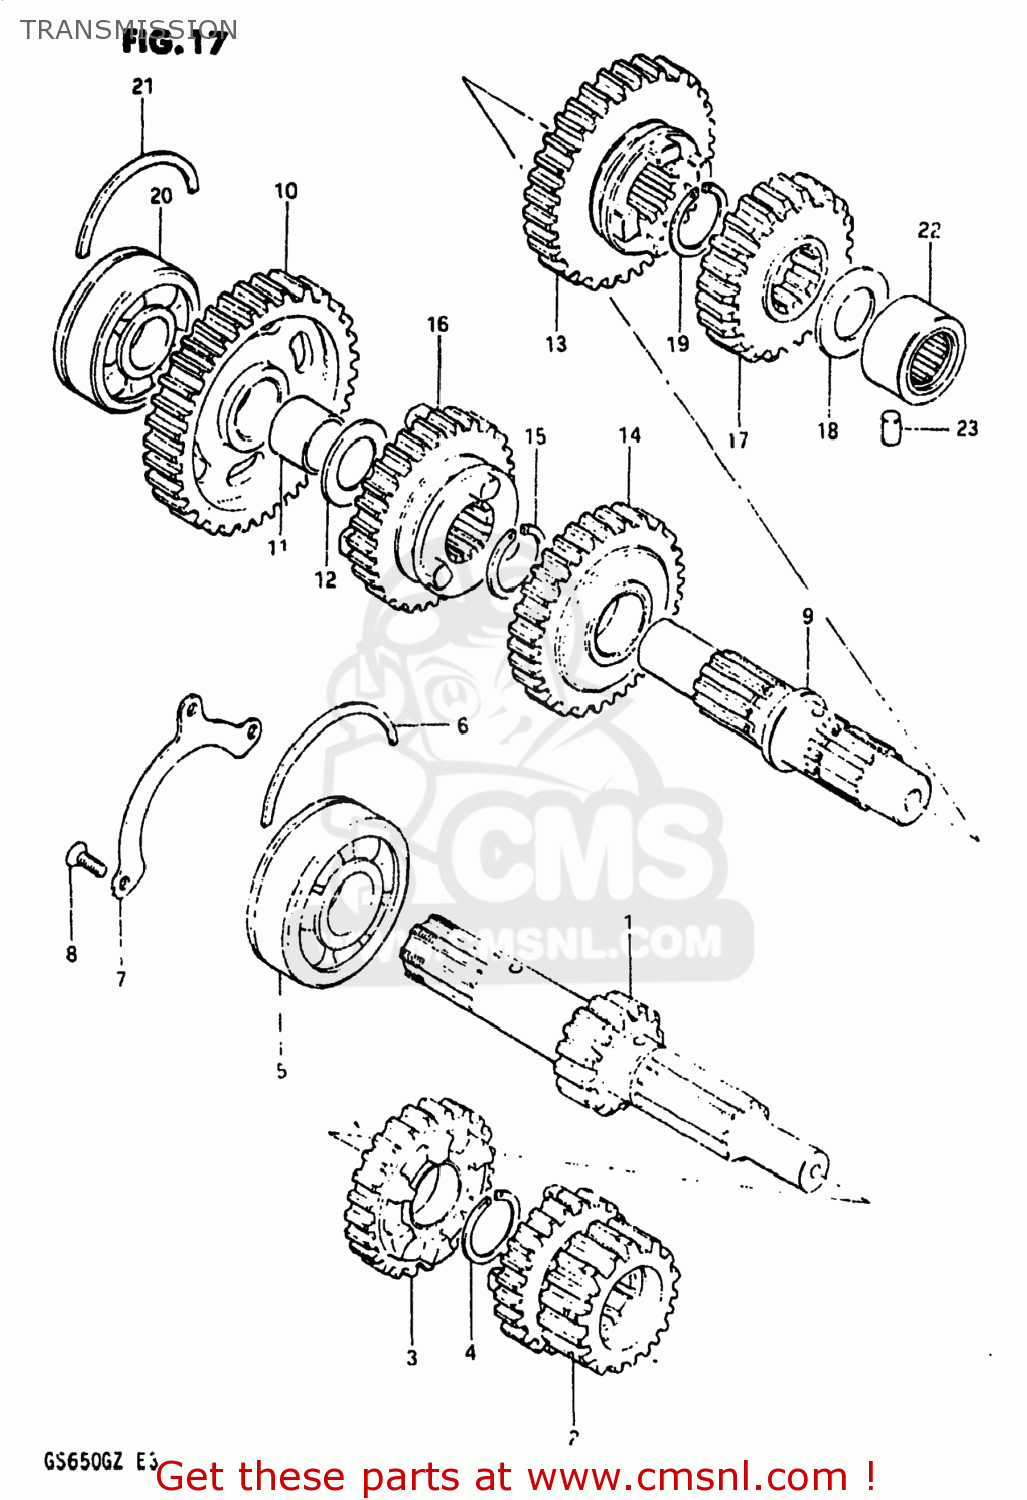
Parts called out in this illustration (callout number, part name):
1	SHAFT,COUNTER
2	GEAR,SECOND DRIVE
3	GEAR,FOURTH DRIVE
4	CIRCLIP
5	BEARING(25X62X17)
6	C-RING
7	RETAINER,CNTR SHAFT BEARING
8	SCREW
9	SHAFT,DRIVE
10	GEAR,FIRST DRIVEN
11	BUSHING
12	WASHER
13	GEAR,SECOND DRIVEN
14	GEAR,THIRD DRIVEN
15	CIRCLIP
16	GEAR,FOURTH DRIVEN
17	GEAR,REDUCTION(NT:24)
18	THRUST WASHER,REDUCTION
19	CIRCLIP
20	BALL BEARING 20X47X14
21	C RING
22	BEARING(20X34X16)
23	PIN
